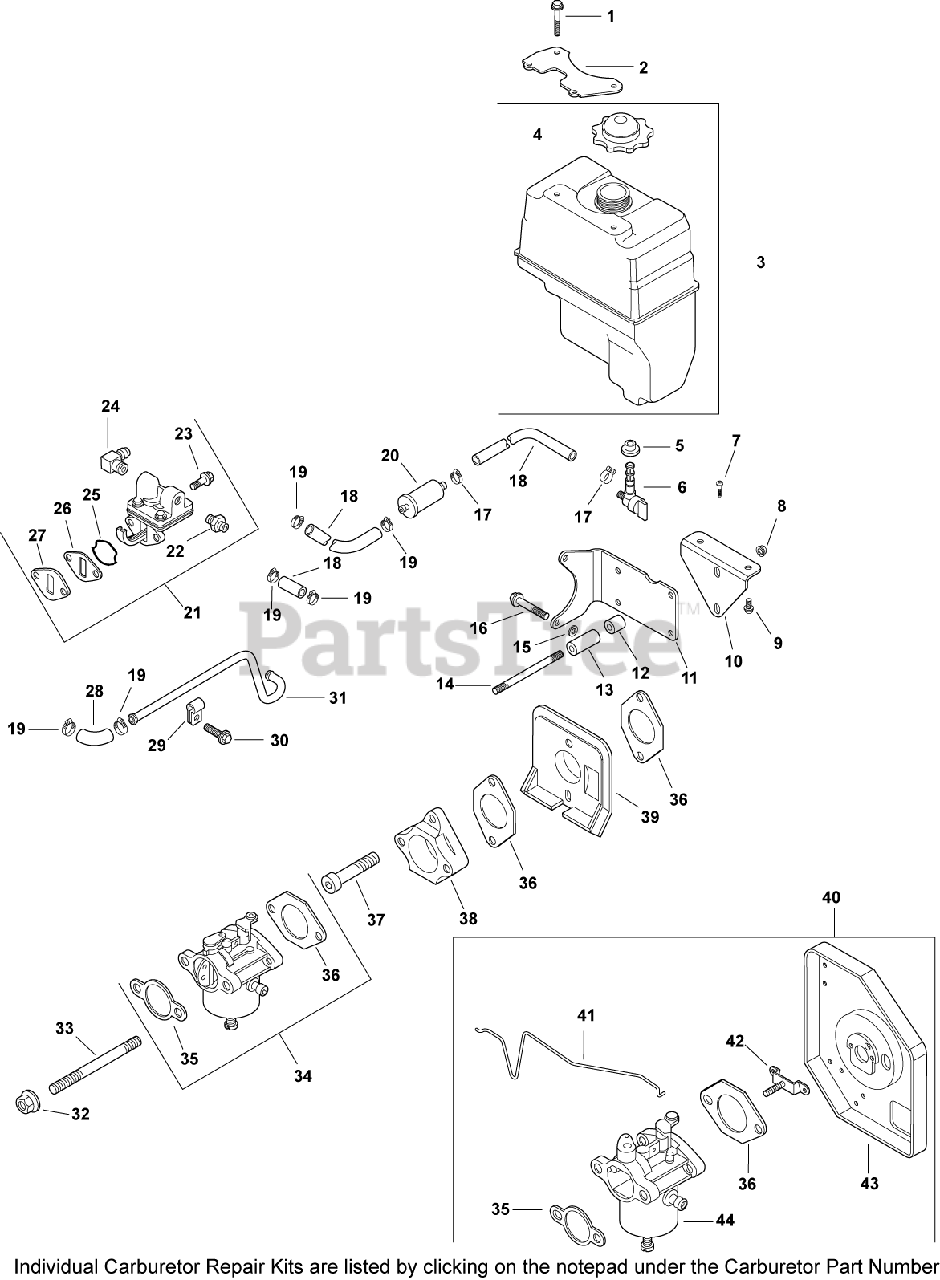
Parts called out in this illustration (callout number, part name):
1	SCREW,FLG THD FRM M6X1.0X25-(#25086395S)
2	BRACKET, FUEL TANK
3	KIT, FUEL TANK
4	CAP, FUEL TANK
5	BUSHING, FUEL TANK
6	VALVE, FUEL SHUT-OFF
7	SCREW, LBD SKT M6x1.0x20-(#25086403S)
8	NUT, FLG M8X1.25
9	SCREW, FLG M6X1.0X12
11	BRACKET, FUEL TANK
13	SPACER, FUEL TANK
14	STUD, M8X1.25X133-USE 25 755 54-S
15	WASHER, FLAT 11/32"
16	SCREW, FLG M8X1.25X50
17	CLAMP, BAND SPRING HOSE-(#2523737S)
18	HOSE,LW PERM.FUEL 24.00"-USE 25 111 81-S
19	CLAMP, HOSE (KM)-USE 25 237 31-S
20	FILTER,FUEL 51 MICRON (FUEL PUMP)
21	KIT, FUEL PUMP
22	KIT, STRAIGHT FITTING
23	SCREW,FLG THD FRM M6X1.0X20-(#25086396S)
24	CONNECTOR, 90 DEG. HOSE
25	O-RING, FUEL PUMP
26	SPACER, FUEL PUMP
27	GASKET, FUEL PUMP
28	HOSE, FUEL LOW-PERMEATION
29	CLIP, TUBE & WIRING (KM)
30	SCREW, FLG THD FRM M5X.8X10
31	LINE, FUEL - DISCONTINUED
32	NUT, FLG M6X1.0
33	STUD,M6X1.0X116
34	KIT, CARBURETOR w/GASKETS
35	GASKET, AIR CLEANER BASE
36	GASKET, CARBURETOR
37	SCREW, SKT CAP M6X1.0X35
38	ADAPTER, CARBURETOR
39	DEFLECTOR, HEAT
40	KIT, CARB. RETROFIT
41	LINKAGE, CHOKE
42	BRACKET, AIR CLEANER
43	BASE, AIR CLEANER
44	CARBURETOR W/GASEKTS - USE 12 853 139-S
